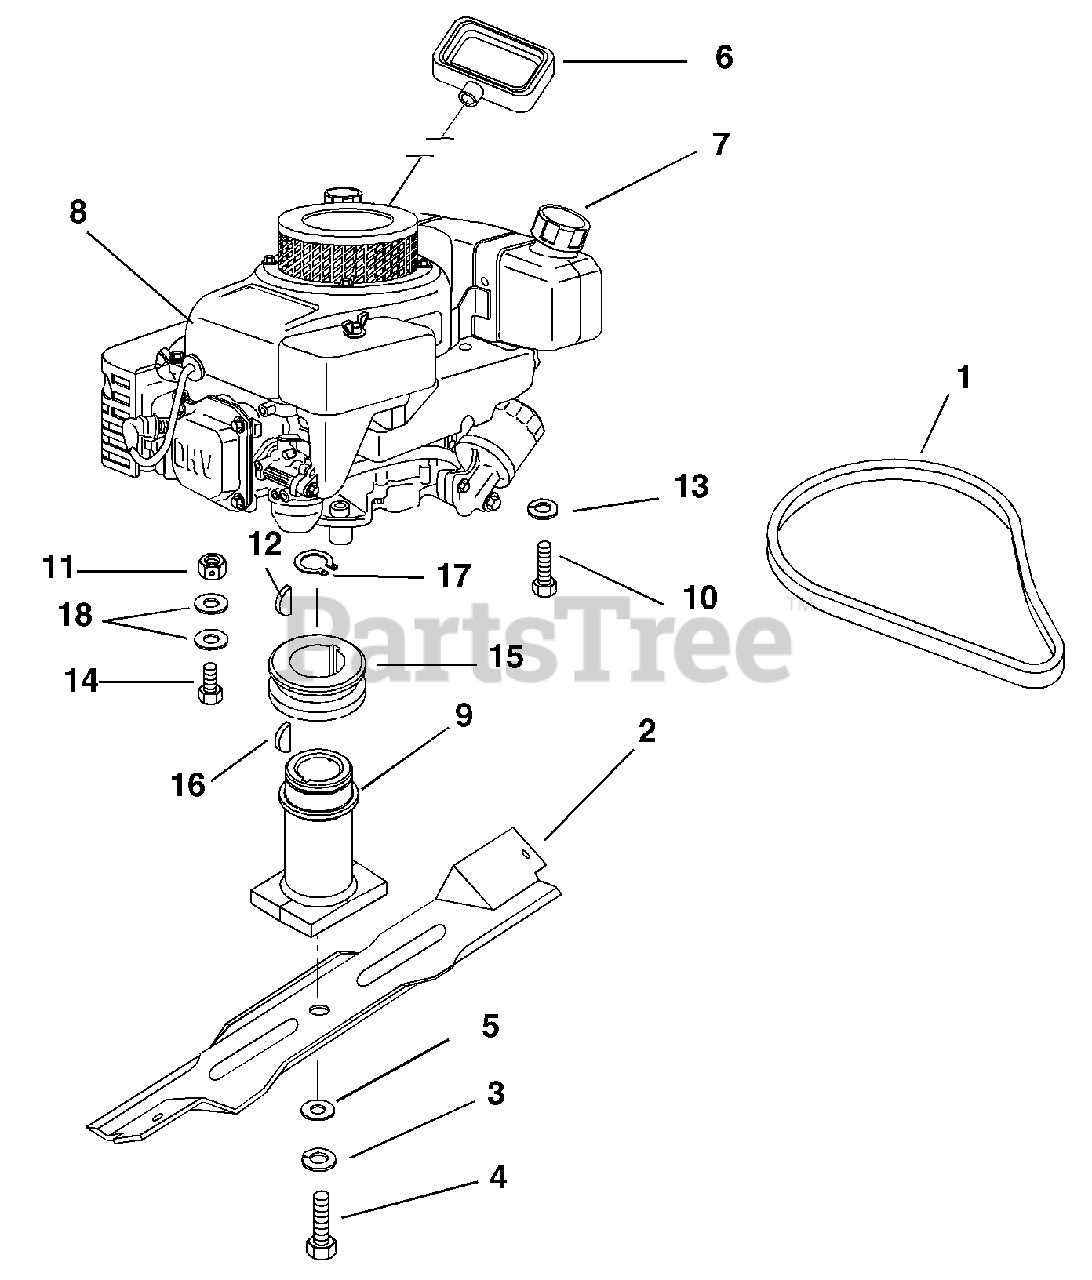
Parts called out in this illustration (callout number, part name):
1	V-Belt 3L Section
2	Blade, 21" Mower
3	Washer-Locking .38 x .094
4	Bolt-Hex .38-24 x 2.00
5	Washer-Flat Steel .390 x 1.50 x .125
6	Recoil Start Handle
7	Fuel Cap
8	Engine, Robin 6 HP 4 Cycle
9	Blade Adapter .875 Dia w/Keyway
10	Bolt-Hex .31-18 x .75 Grade 5
11	Nut-Locking-Center .31-18
12	Key-Wooddruff .156 x .625 x .25
13	Washer-Locking .312 x .097
14	Bolt-Hex .31-18 x 1.25 Grade 5
15	Sheave-2.94 x 1.378
16	Key-Woodruff .13 x .38
17	Ring-Retaining
18	Washer-Flat-Steel .312 x .734 x .065
